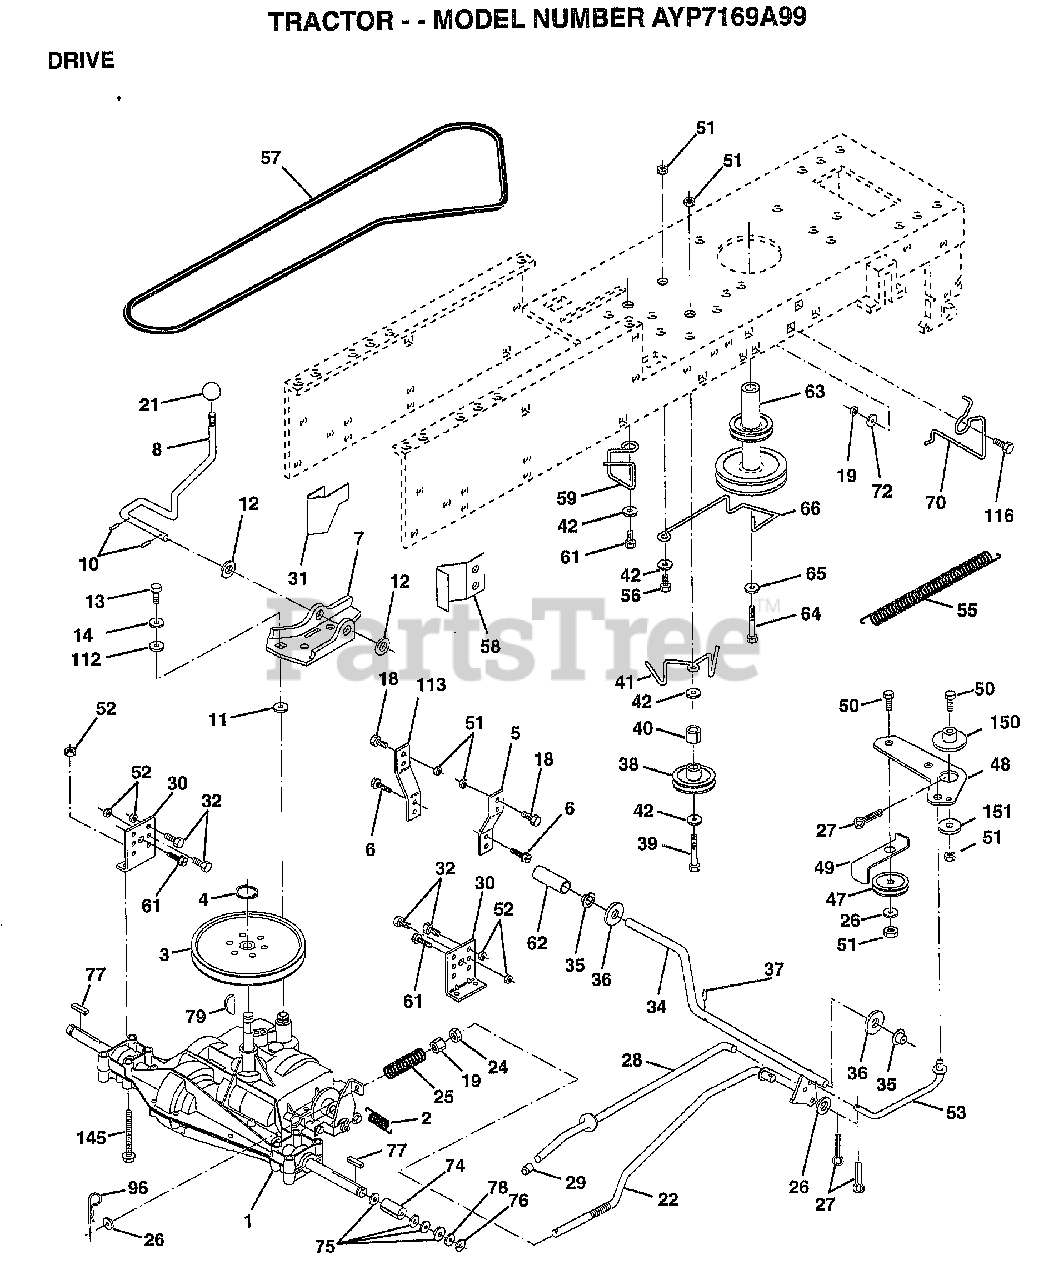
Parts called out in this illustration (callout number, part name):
2	SPRING.BRAKE.RETU
3	PULLEY TRANS
5	STRAP TORQUE
6	SCREW
7	BRKT.SADDLE.SHIFT
8	SHIFT ROD
10	PIN COTTER 1/8
11	WASH-SHFT PLT LT
12	WASHER
13	BOLT.1/4-28.W/PAT
14	LOCKWASHER
18	BOLT
19	NUT
21	KNOB T (1/2-HOLE)
22	BRAKE ROD
24	NUT
25	SPRING ROD LT
26	WASHER
27	COTTER PIN
28	ROD.BRAKE.PARK.LT
29	PLUNGER CAP T
30	TRANSAXLE MTG BKT
31	"KEEPER,BELT LH T"
32	BOLT
34	SHAFT ASM-PEDAL F
35	NYLON BEARING
36	WASHER LT
38	FLAT IDLER PULLEY
39	BOLT
40	SPACER T
41	"KEEPER,BELT.IDLER FLAT"
42	WASHER
48	BELLCRANK.CLUTCH
49	RETAIN BELT
53	"LINK, CLUTCH T"
55	"SPRING, RETURN LT"
58	"KEEPER,BELT RH T"
59	KEEPER BELT CNTSP
61	SCREW
62	PEDAL COVER T
63	PULLEY.ENGINE
64	BOLT
65	LOCKWASHER
66	KEEPER-BELT
70	KEEPER BELT ENG
72	WASHER
74	SPACER AXLE
75	WASHER
76	E-RING LT
77	SQUARE KEY
78	WASHER
96	RETAINER M
112	WASHER LT
113	"STRAP,TORQUE"
116	BOLT RDHD 3/8-16
145	BOLT.HEX.FLGHD
150	BUSHING.BELLCRANK.GRD.DR
151	WASHER
